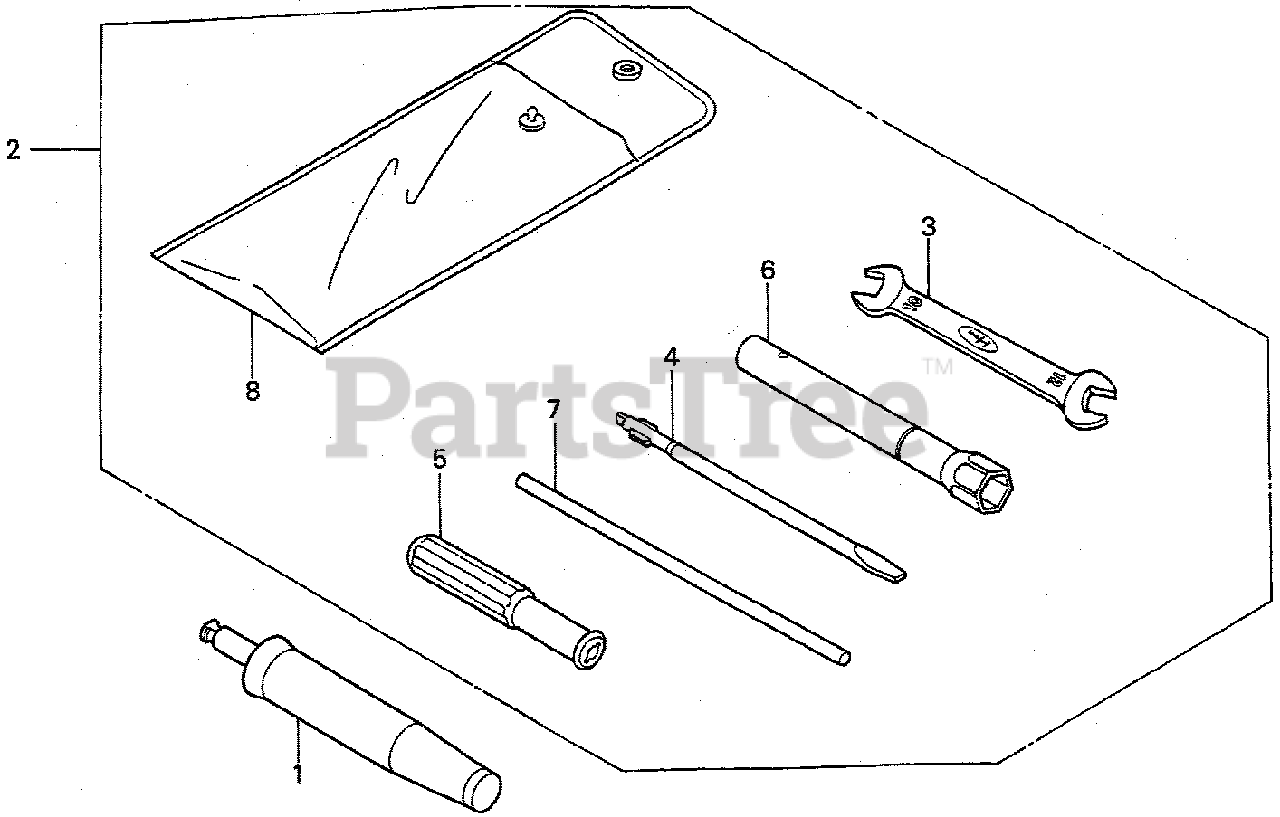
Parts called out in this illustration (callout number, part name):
1	CONNECTOR, MALE
2	TOOL KIT (N/A: SEE COMPONENTS)
3	WRENCH (10X12) (OPEN END)
4	SCREWDRIVER 3, STRAIGHT SLOT (NO.2)
6	WRENCH, BOX (P21)
7	BAR A, HANDLE
